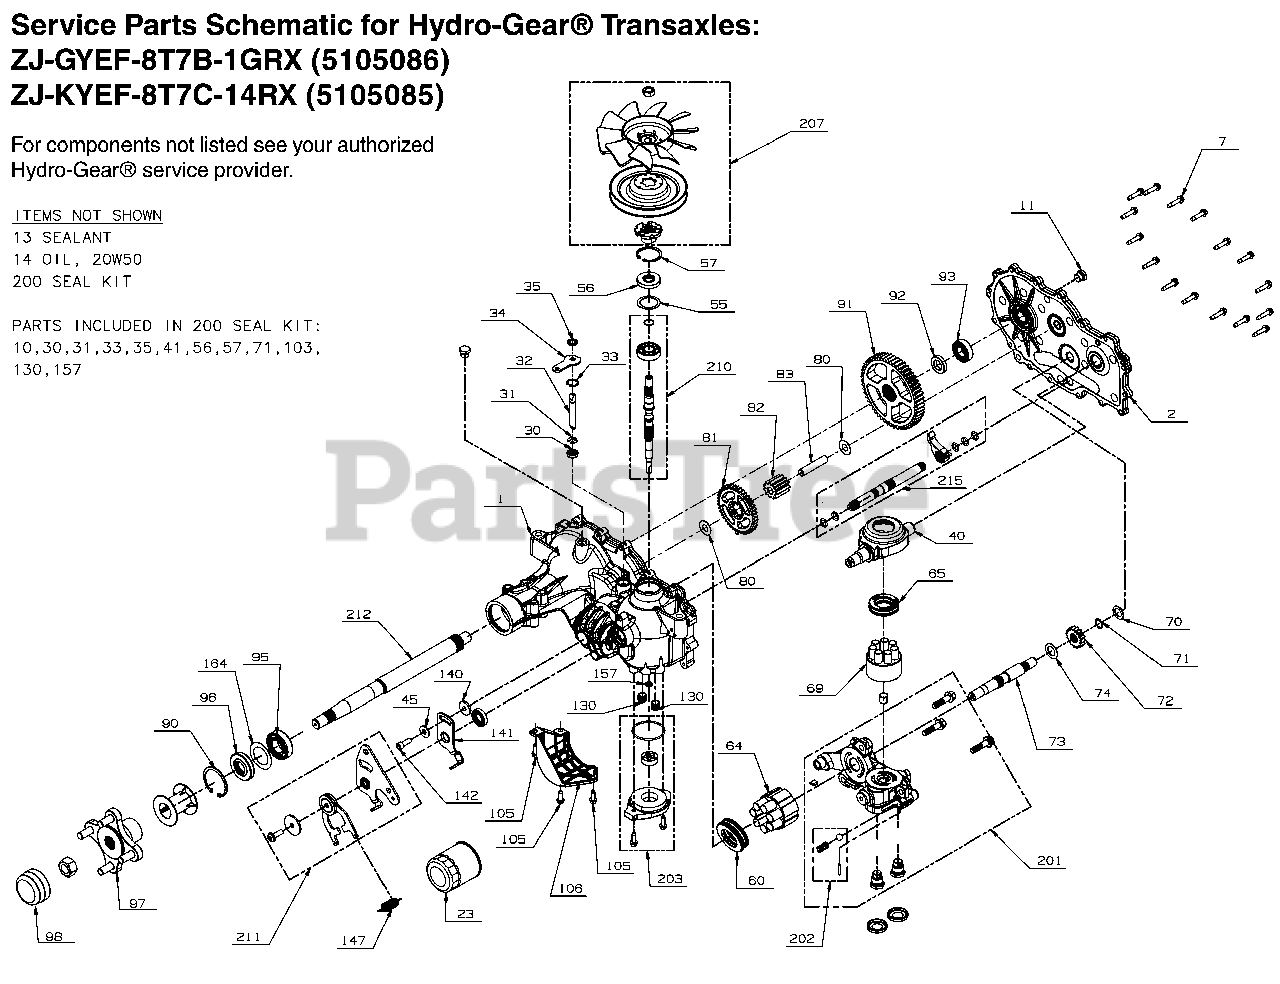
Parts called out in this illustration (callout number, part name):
1	KIT, MAIN HOUSING, RH, CHRG, CNTRL
2	KIT, SIDE COVER RH
23	FILTER, OIL, ZT2800
34	ARM, BYPASS
35	RING, RETAINING .375 EXTERNAL
40	SWASHPLATE, TRUNNION
56	OUTPUT SHAFT SEAL, 17X40X7, HR #51161
57	RING, RET 2.06 INT,
64	KIT, 16cc CYLINDER BLOCK ASSEMBLY
69	KIT, BLOCK 7 PISTON
70	WASHER, .63 X 1.00 X .05 FLAT
71	RETAINING RING, MOTOR SHAFT
72	GEAR, 16T (STEEL)
73	SHAFT, MOTOR
74	WASHER, .71 X 1.16 X .04 FLAT
80	WASHER, .51 X 1.00 X .03 FLAT
82	GEAR, 11T (STEEL)
83	PIN, JACKSHAFT
90	RING, RETAINING 2.25 INTERNAL
93	KIT, BEARING
95	BEARING BALL, 1.0 X 52 X 15 OPEN 6205M
96	KIT, SEAL, AXLE - HG# 53699
97	ASSM, HUB
98	AXLE CAP,
106	GUARD, FILTER, RH
130	TUBE, CHARGE TRIPLE O-RING
141	ARM, NEUTRAL RIGHT
142	SHCS, 5/16-24 X .875 (PATCH)
147	SPRING, EXTENSION
157	KIT, GEROTOR SEAL
164	WASHER, 1.355 x 2.035 x .021 FLAT
200	KIT SEAL
201	KIT, CENTER SECTION, RH CHARGE
202	KIT, CHARGE RELIEF
203	KIT, CHARGE
207	KIT, FAN/PULLEY
210	KIT, INPUT SHAFT
211	KIT, RTN BIDIRECTIONAL
212	SHAFT, AXLE
215	KIT, OUTBOARD, RH ROT A / LH ROT B
